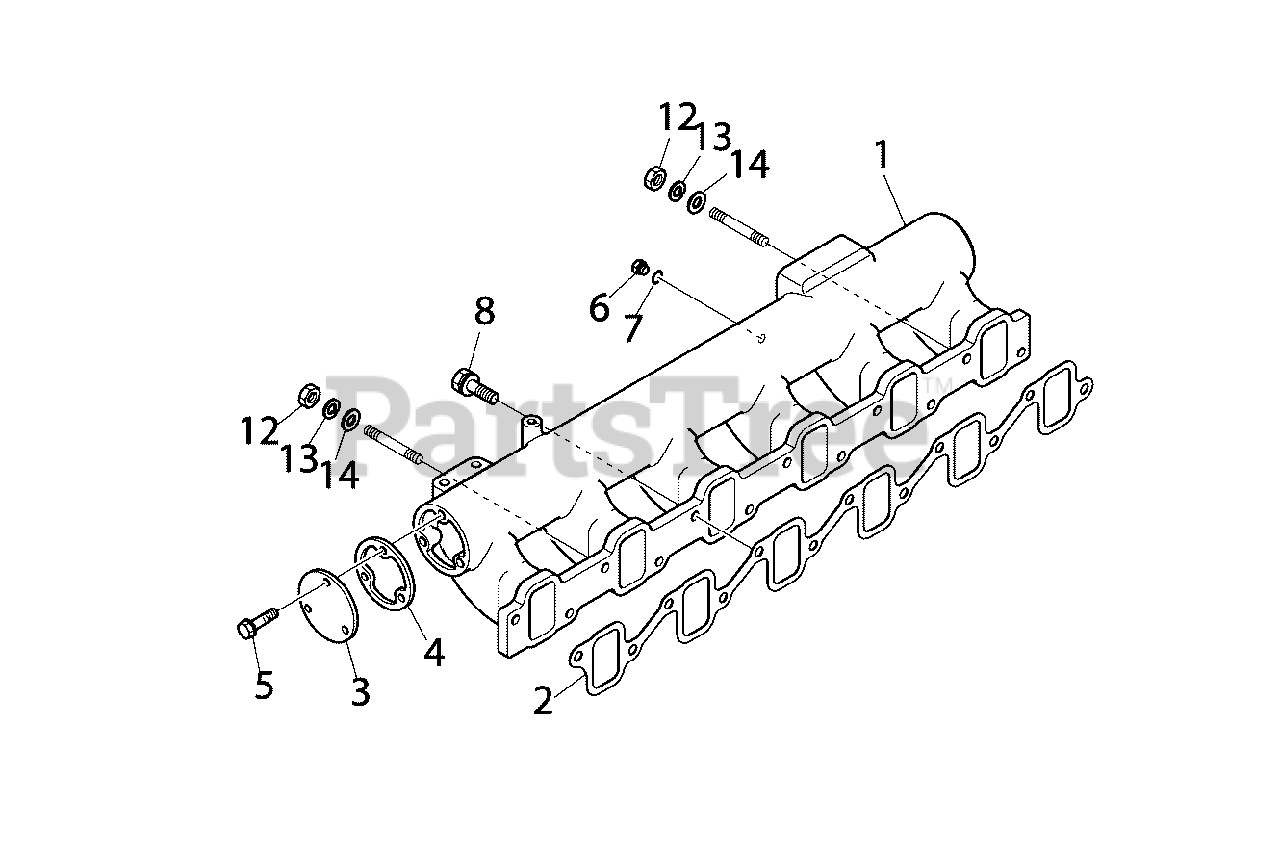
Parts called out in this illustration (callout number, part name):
1	* MANIFOLD, INTAKE
2	GASKET, INTAKE MANIFOLD
3	* FLANGE
4	GASKET, INTAKE MANIFOLD
5	* BOLT
6	* PLUG, SCREW
7	* SEAL, RING
8	* BOLT
12	* NUT, HEX
13	* WASHER, SPRING
14	* WASHER
